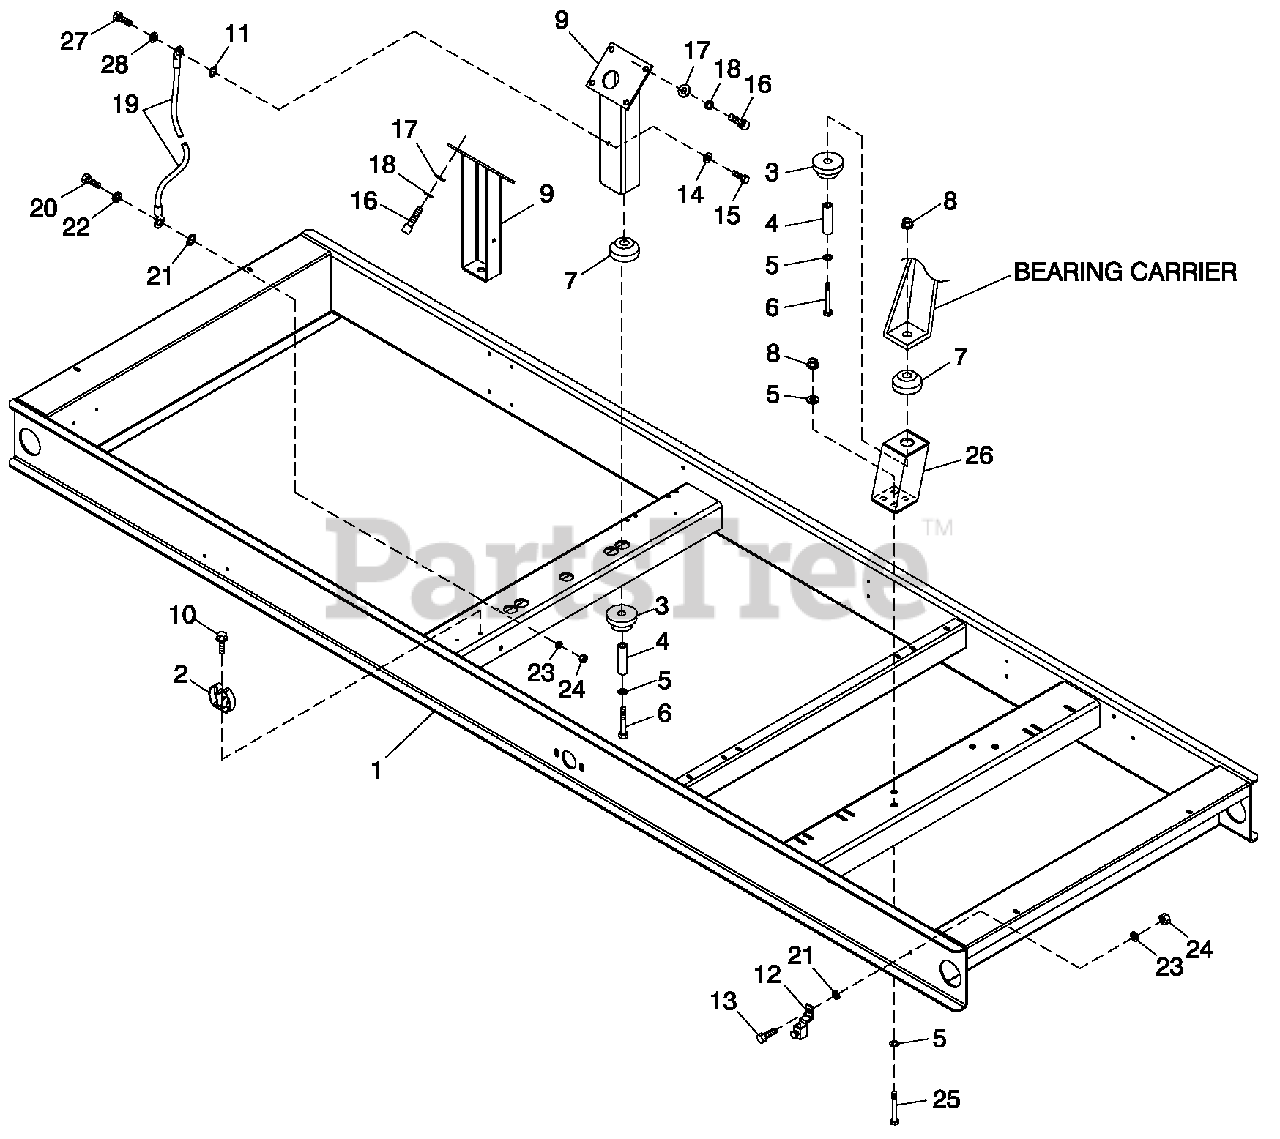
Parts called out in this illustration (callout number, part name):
1	BASE CP 80KWGB-150KW 2P
2	SPRING CLIP HOLDER ,37-.62
3	DAMPENER VIBRATION
4	SPACER .49 X .62 X 1.87 PWDR/ZINC
5	WASHER FLAT M12
6	SCREW HHC M12-1.75 X 85 G8.8
7	DAMPENER VIBRATION 50 WHITE
8	NUT LOCKING M12-1.75
9	SUPPORT ENG 5.4L LH/RH 6.8L RH
10	SCREW HHTT M4-0.7X8BP
11	WASHER SHAKEPROOFINT1/4
12	LUG SOLDERLESS 3/0-#4X 13/32 CU
13	SCREW HHC M8-1.25 X 25 G8.8
14	WASHER FLAT 1/4-M6 ZINC
15	NUT HEX M6X 1.0 G8YEL CHR
16	SCREW SHC M10-1.5 X 30 G12.9
17	WASHER FLAT 3/8-M10 ZINC
18	WASHER LOCK M10
19	ASSY WIRE 14.00"
20	SCREW HHC M8-1.25 X 30 G8.8
21	WASHER SHAKEPROOF INT 3/8
22	WASHER LOCK M8-5/16
23	WASHER FLAT 5/16-M8 ZINC
24	NUT HEX M8-1.25 G8 YEL CHR
25	SCREW HHC M12-1.75 X 40 G8.8
26	TOWER GB COMPROD C5
27	SCREW HHC M6-1.0X 30 G8.8
28	WASHER LOCK M6-1/4
